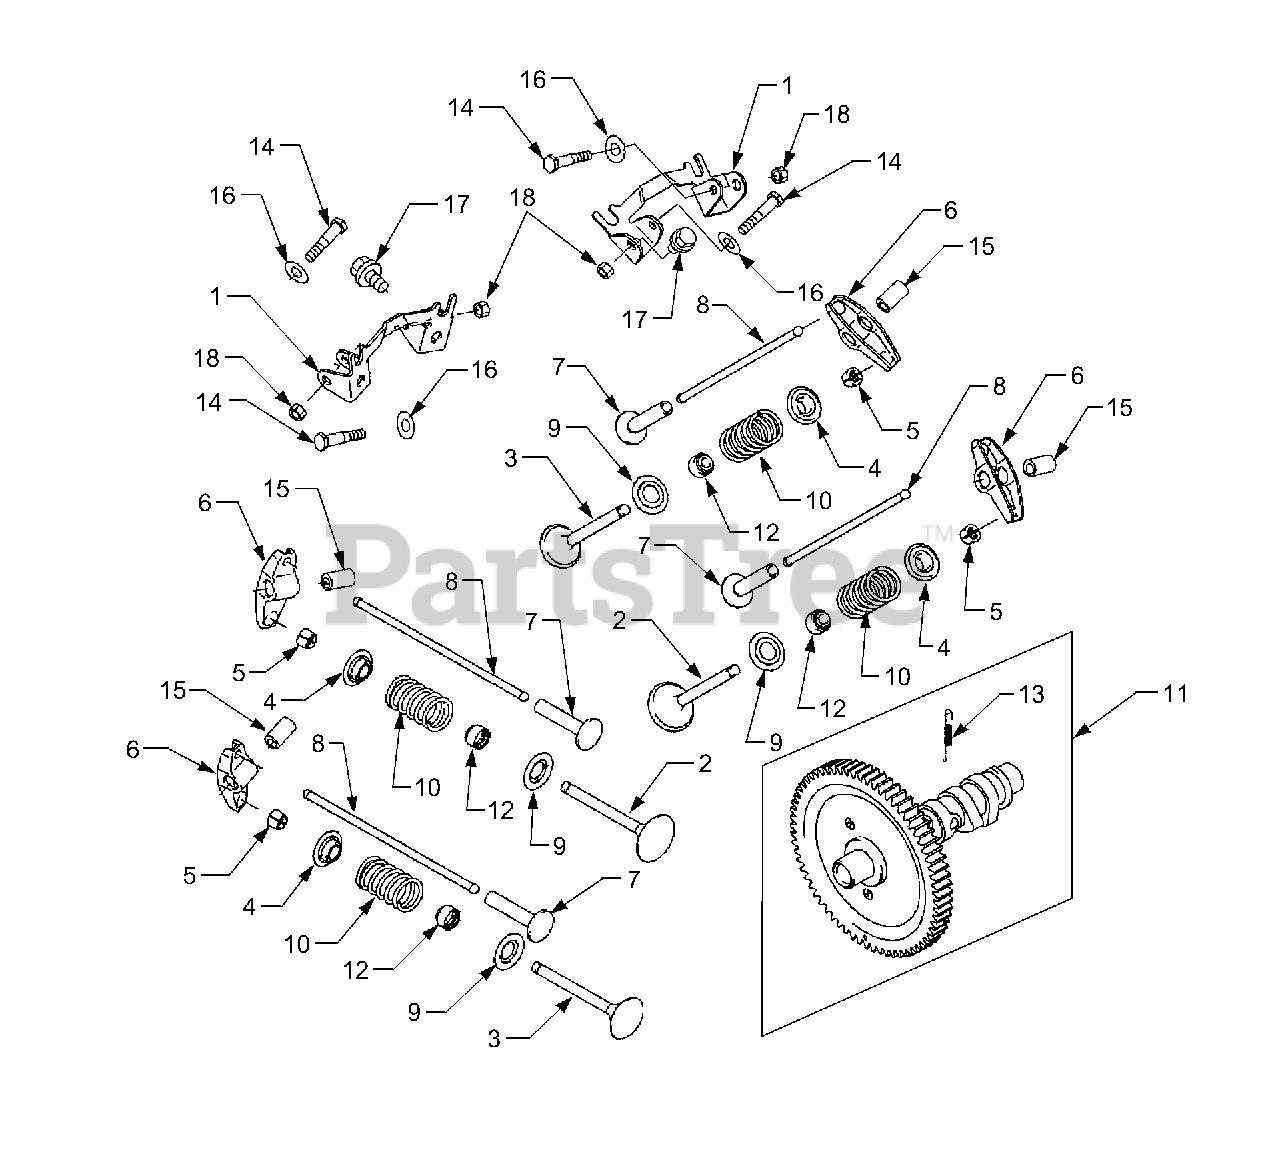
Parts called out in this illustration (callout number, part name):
2	Valve, Intake
3	Valve, Exhaust
4	Retainer, Valve Spring
6	Arm, Rocker
10	Spring, Valve
16	Washer, 8.1 x 18 x .5
17	Bolt, Flanged
18	Nut, Hex
